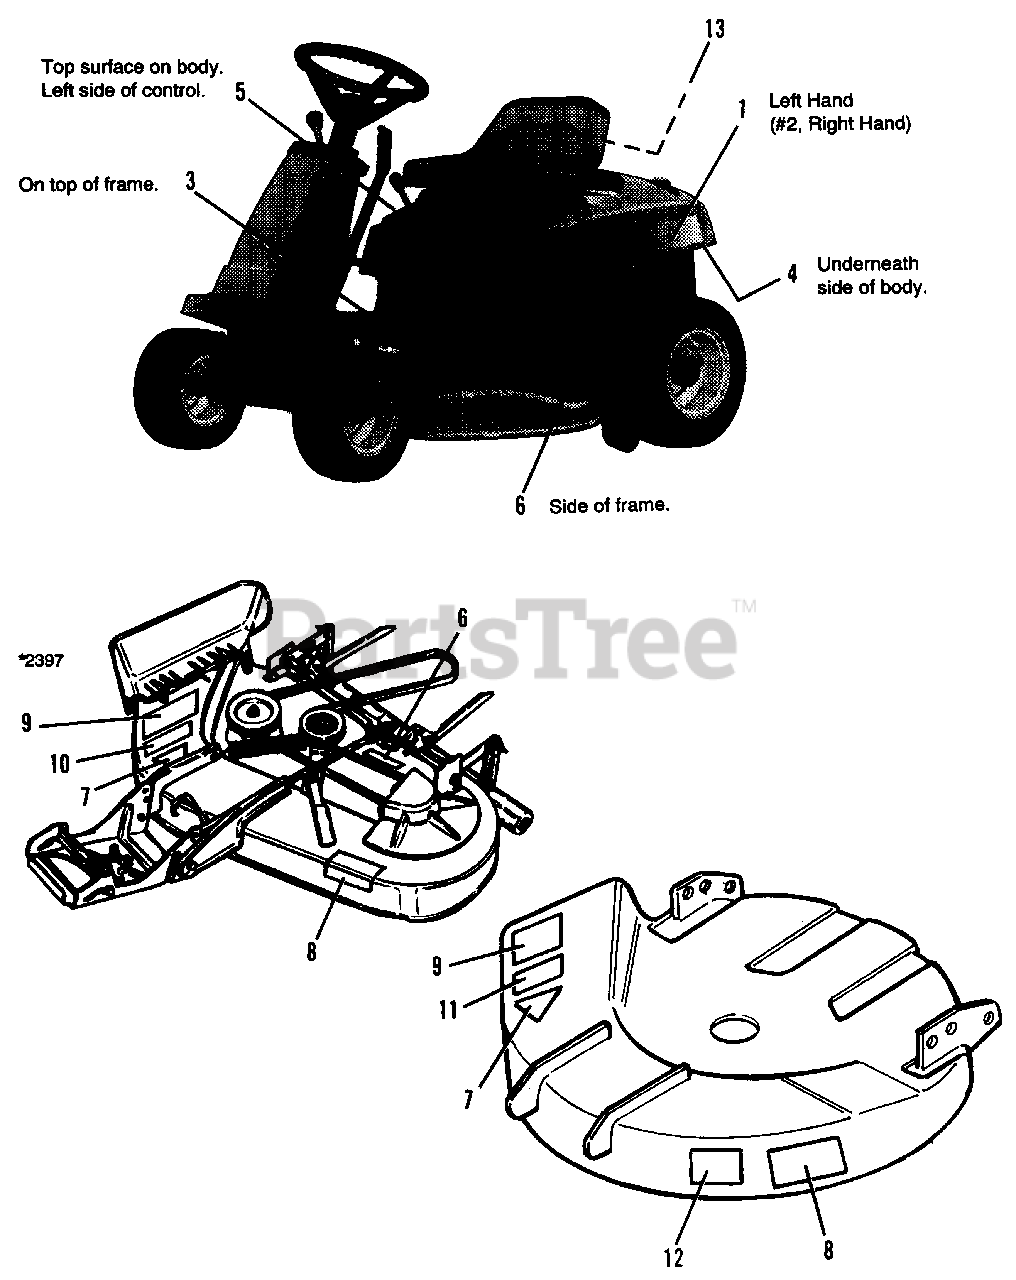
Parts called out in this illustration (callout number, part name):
1	DECAL, Seat Deck, L.H., 12.5 HP (Gear)
1	DECAL, Seat Deck, L.H., 8.5 HP (Gear)
1	DECAL, Seat Deck, L.H., 12.5 HP (Hydro)
2	DECAL, Seat Deck, R.H., 12.5 HP (Gear)
2	DECAL, Seat Deck, R.H., 8.5 HP (Gear)
3	DECAL, Instructional
4	DECAL, Belt & Blade
5	DECAL, Throttle/Choke
6	I.D. PLATE
7	DECAL, OPEI
8	DECAL, Danger (Hand Under Deck)
9	DECAL, Danger (Chute In Place)
10	DECAL, Cutting Width-34"
11	DECAL, Cutting Width-30"
12	DECAL, Mulcher
13	DECAL, USA (Seatback)
